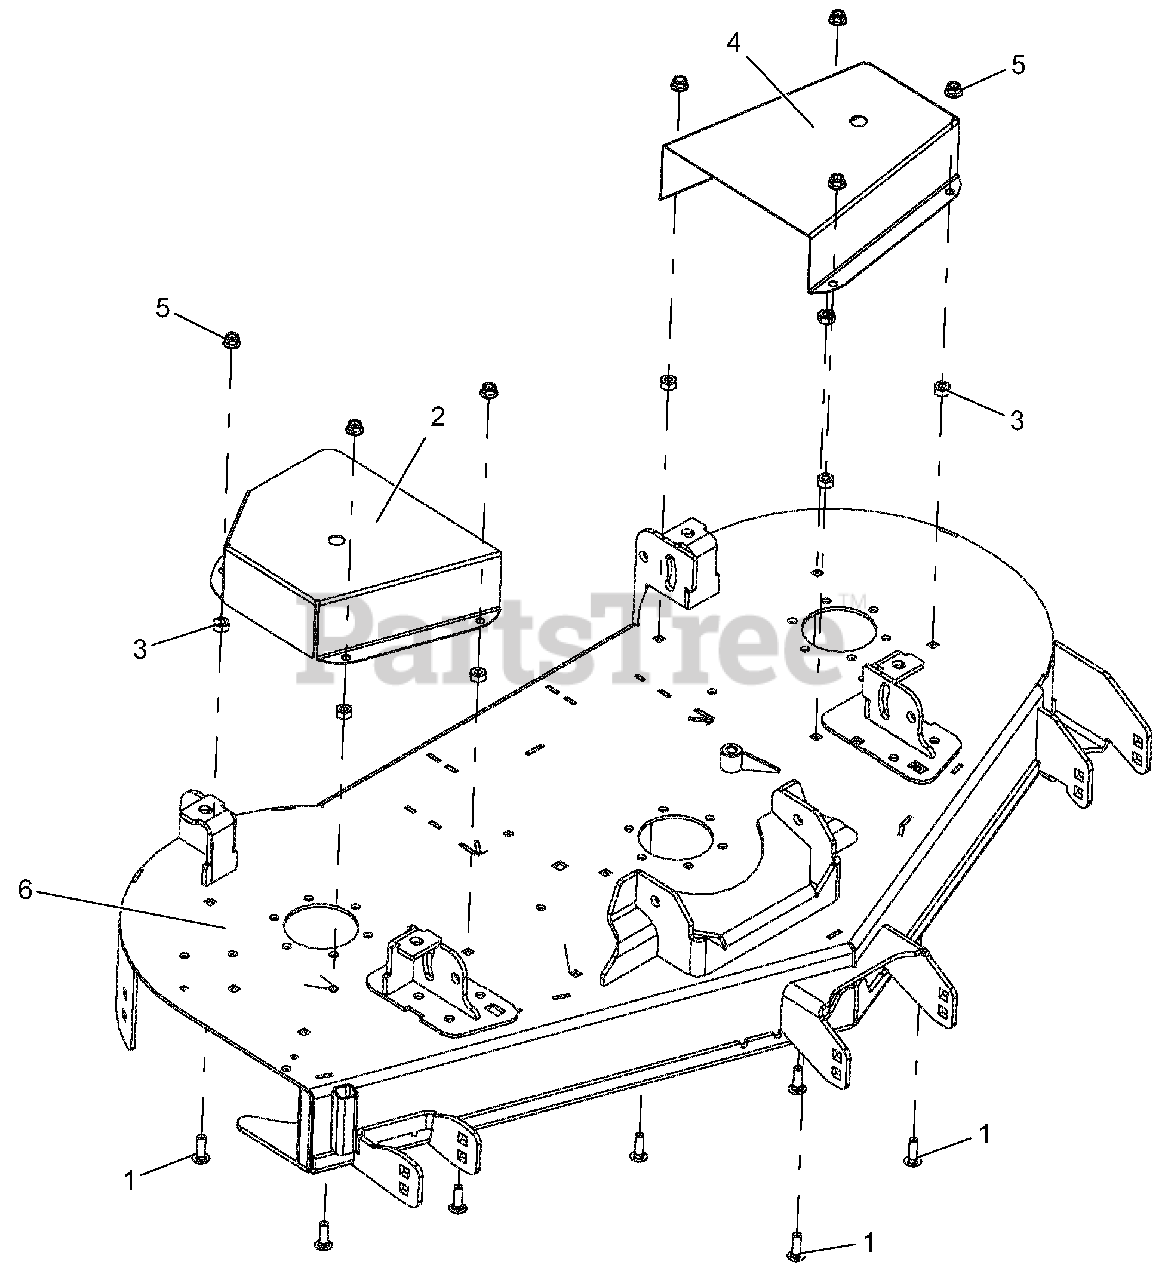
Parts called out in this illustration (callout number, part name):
1	BLT-RDHDSQNK .38-16 x 1.25 G5 YWZC
2	GUARD, 52" RH DECK BELT
3	NUT-HEAVY HEX .38-16 YWZC
4	GUARD, 52" LH DECK BELT
5	NUT-LK-NYL-FLG .38-16 YWZC
6	ASSY, 52" DECK WITH DECALS
